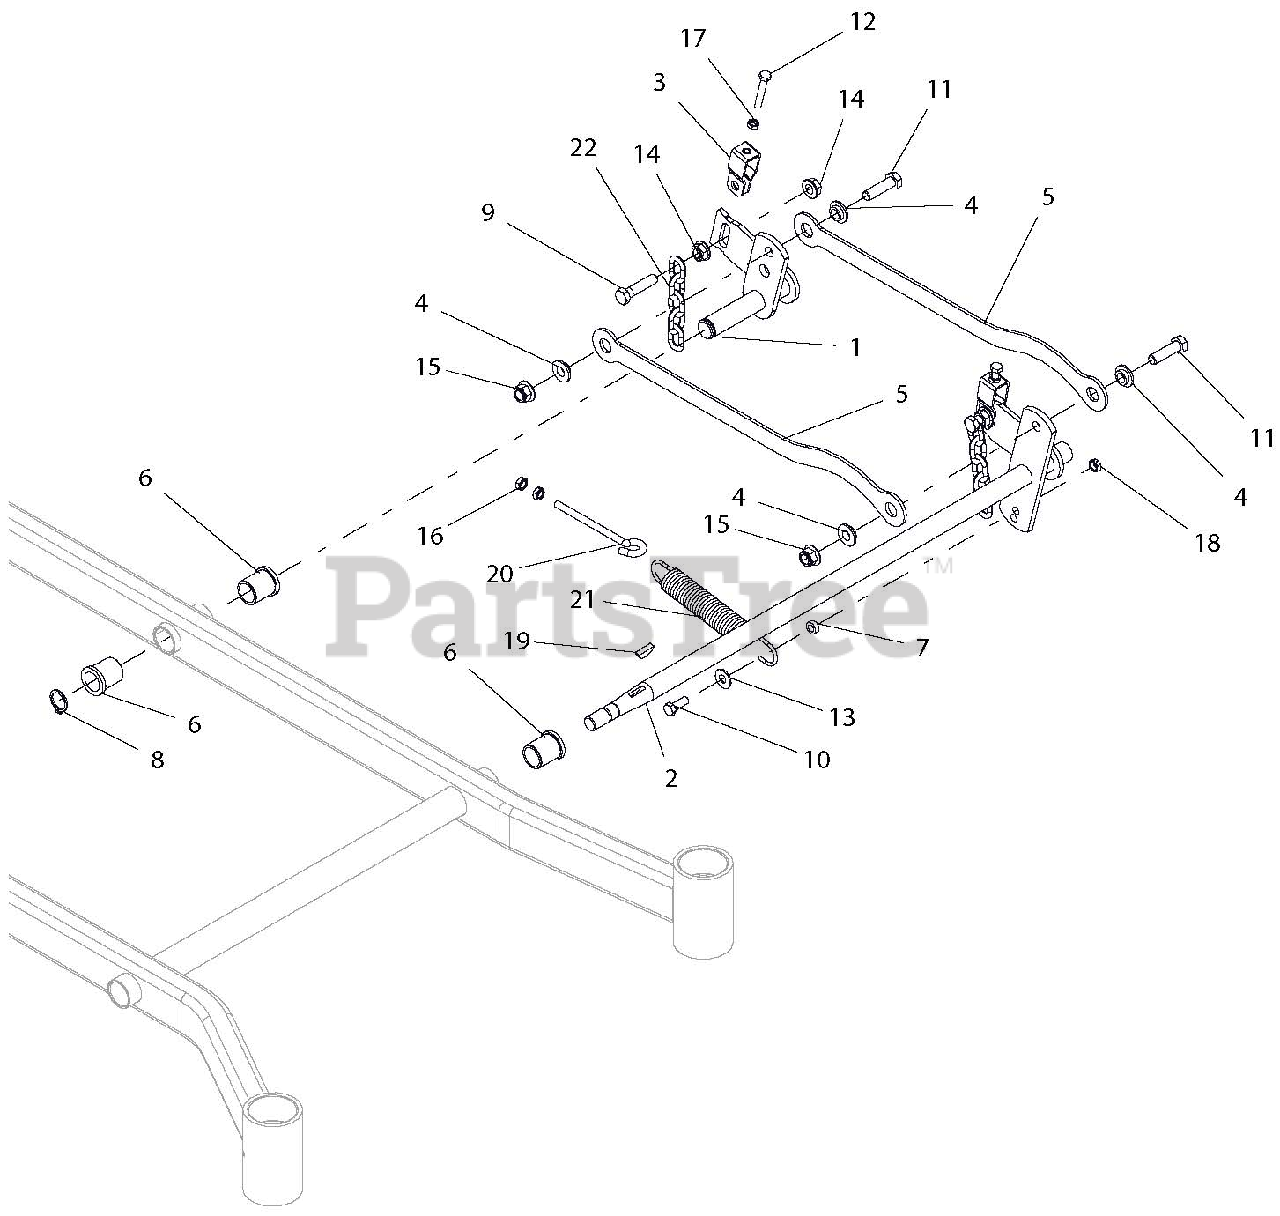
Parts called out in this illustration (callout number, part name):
1	WLDMT, REAR LH DECK LIFT
2	WLDMT, FRONT LH DECK LIFT ARM-BLACK
3	BRKT, DECK LEVELING
4	BSHG, FLANGE .515X.750X.31X1.12
5	LINK, LIFT - BLK
6	BSHG-FLG 1.00X1.25X1.5X1.5
7	BSHG, SLV .377X.624X.235
8	RG-RTNG-EXT 1.00X.078
9	BLT, HEX M12-1.75X50 CLS8.8 YZ
10	BLT-HEX .38-16X1.00 GR5 YWZC
11	BLT-HEX .50-13X1.75 GR5 YWZC
12	BLT-HEX .31-18X2.00 FTH GR5 YWZC
13	WSHR-FL-STL.438X1.00X.083 YWZC
14	NUT, SPLK -FLG M12-1.75 YZ
15	NUT-LK-NYL-FLG .50-13 YWZC
16	NUT, JAM .375-16 YWZC
17	NUT, JAM .312-18 YWZC
18	@NUT-LK-CTR-JAM .375-16 YWZC
19	KEY, WDRF .25 X 1.00 HRD #15
20	BOLT, EYE .38-16X6.00 .62 DIA
21	SPRG, TENSION .162 X 1.250 X 8.250
22	CHAIN, MOWER LIFT
